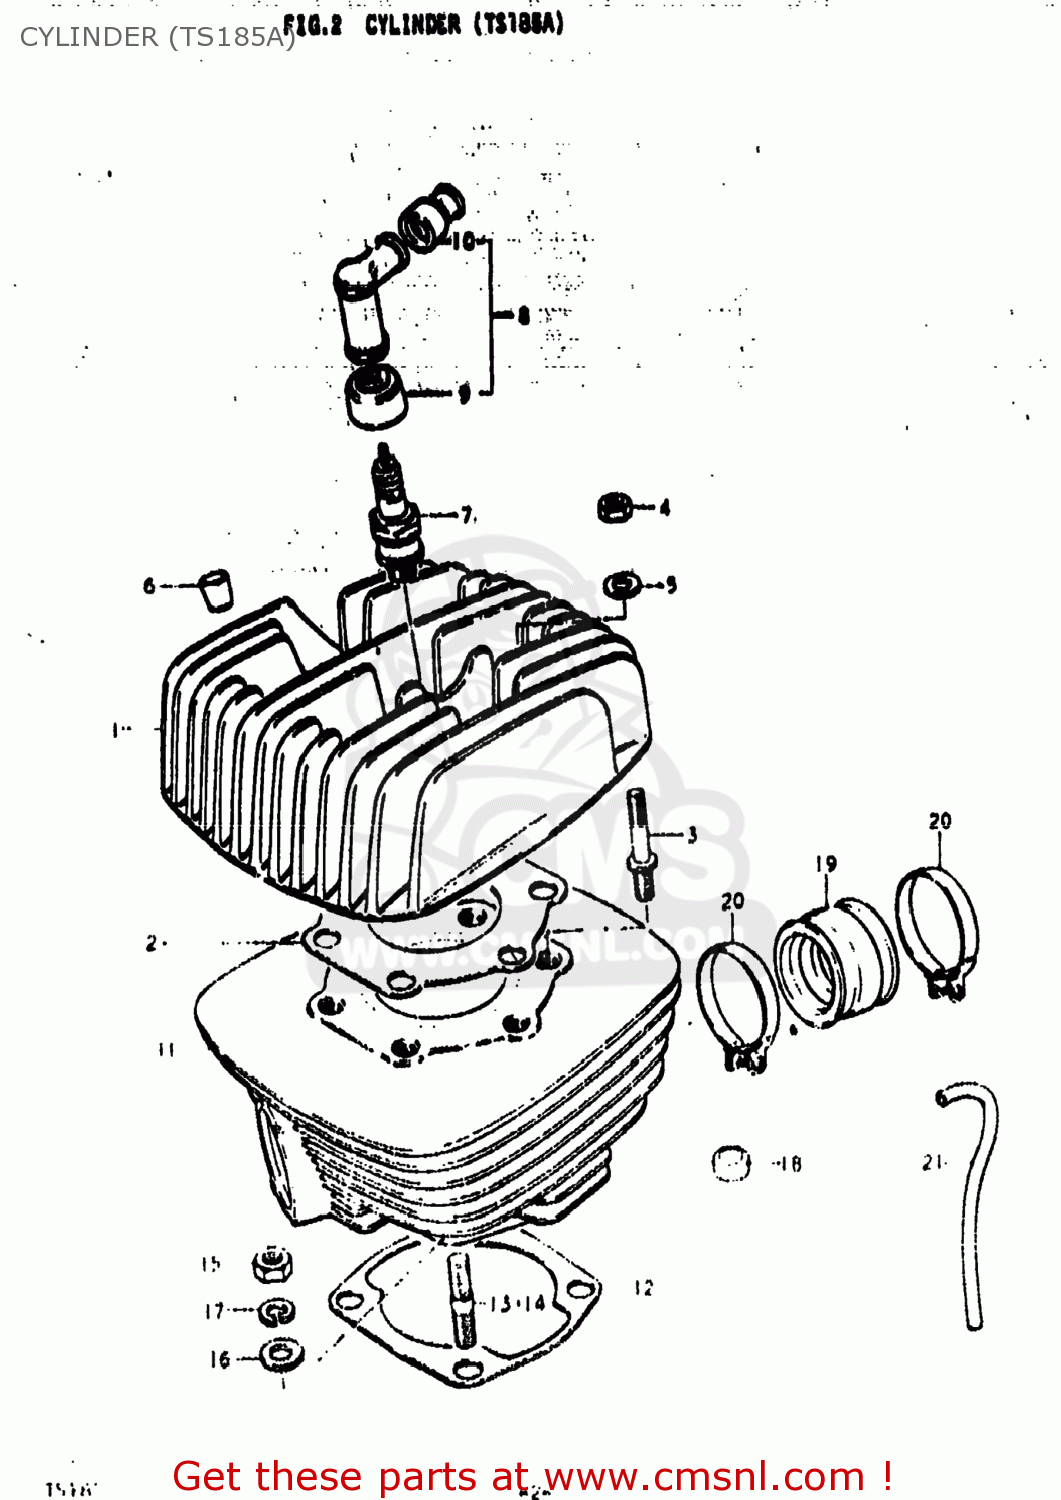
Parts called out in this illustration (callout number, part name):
1	HEAD,CYLINDER
2	GASKET,CYLINDER HEAD (MCA)
3	BOLT,STUD
4	NUT (8MM)
5	WASHER
6	PAD,CYLINDER HEAD
7	PLUG,SPARK(B7HS)
8	CAP,SPARK PLUG
9	SEAL,SPARK PLUG
10	SEAL,SPARK PLU
11	CYLINDER
12	GASKET,CYLINDER (ASB) (MCA)
13	STUD 10X25
14	TAPBOUT
15	NUT
16	WASHER
17	LOCK WASHER
18	PAD,CYLINDER
19	PIPE,INTAKE
20	CLAMP
21	HOSE
